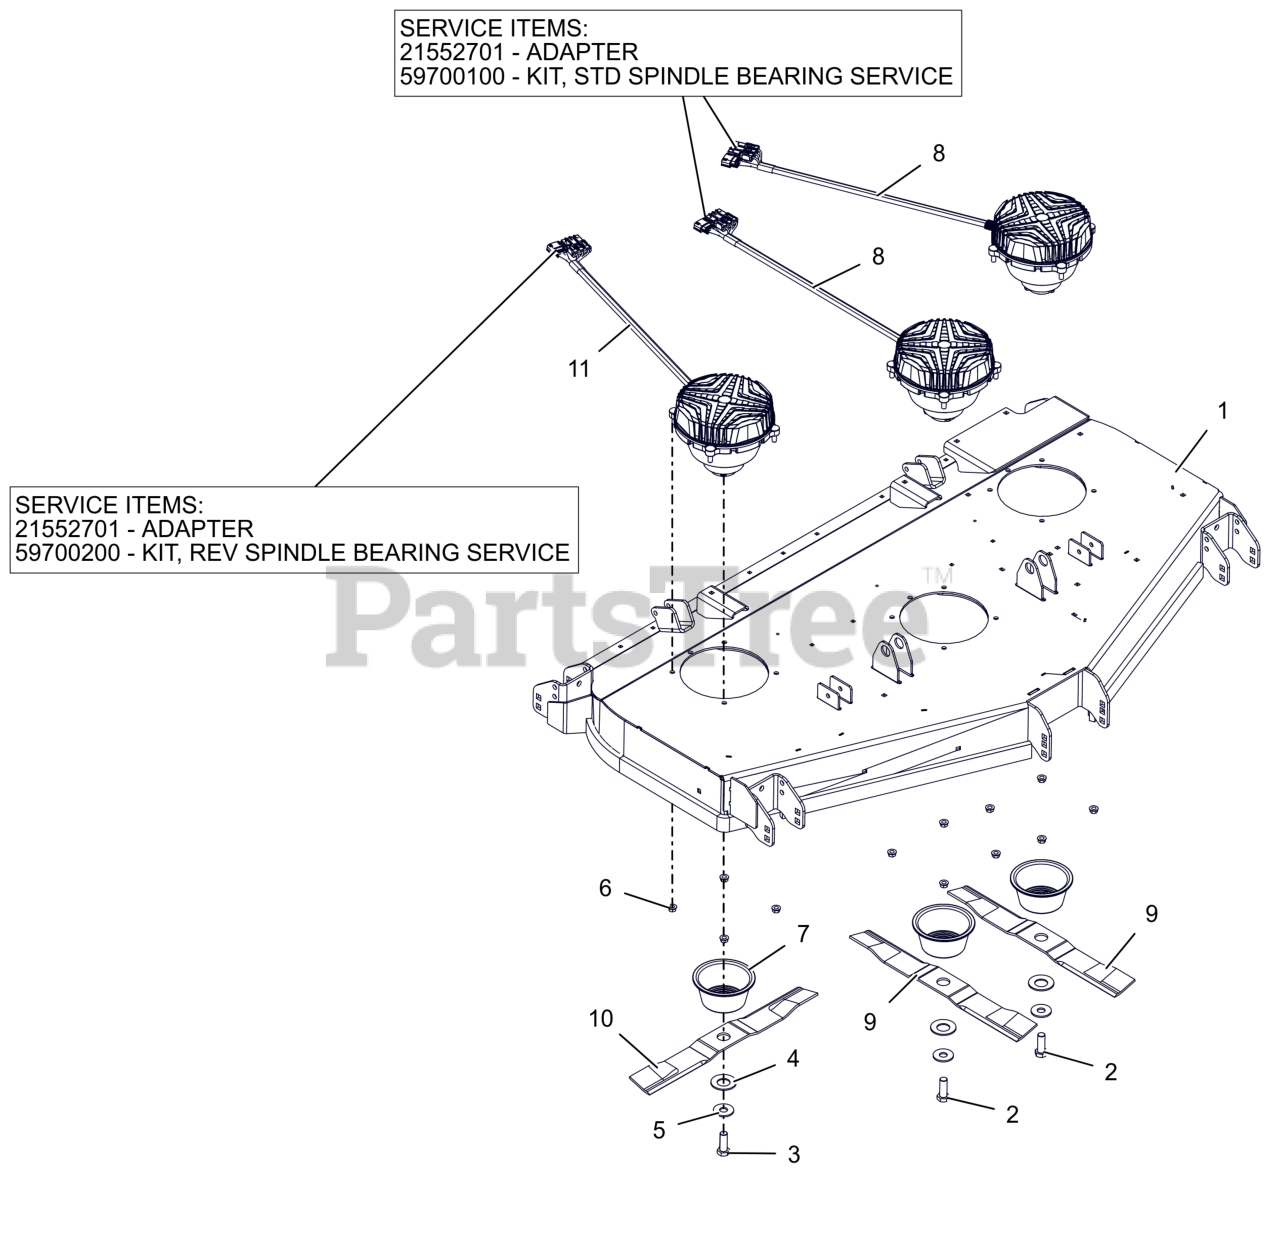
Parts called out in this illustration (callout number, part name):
1	WLDMT, 60" PSEV REAR DISCHARGE DECK (ORANGE)
2	BLT, HEX .62-18X1.75 G8 ZCC
3	BLT, HEX 0.625-11X1.75 GR8 ZCC LH
4	WSHR, BLVL - .56X28.5X3 PHOS.COAT
5	WSHR, HRDN 0.687X1.75X0.134 HRD
6	NUT-LK-CTR-FLG .375-16 GF ZCC
7	GUARD, SPINDLE LOWER
8	MOTOR, SPINDLE-CW
8	ADAPTER
8	KIT,STD SPINDLE BEARING SERVICE
9	BLADE, MOWER 20.5"
10	BLADE, MOWER - 20.5" EFF CCW
11	MOTOR, DECK SPINDLE -CCW
11	ADAPTER
11	KIT,REV SPINDLE BEARING SERVICE
